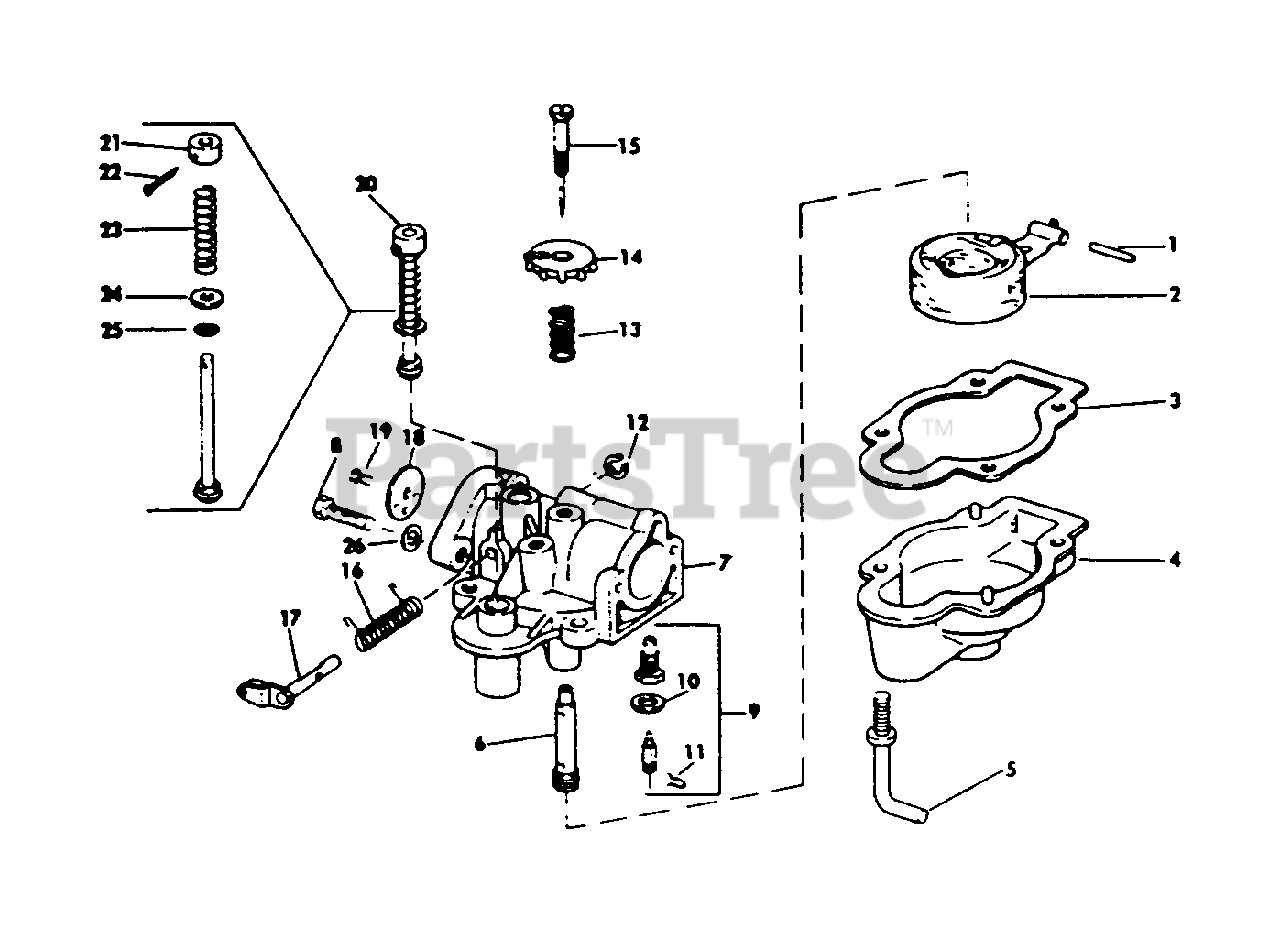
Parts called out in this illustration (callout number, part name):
1	Pin-Float Arm Hinge
2	Float & Arm Assy.
3	Gasket-Float Chamber
4	Chamber-Float
5	Screw-Float Chamber
7	Carb. Body Assy.
9	Float Valve & Seat
10	Washer-Float Valve Seat
11	Clip
12	Grip Ring
13	Spring-Needle Adj.
14	Knob-Needle Adj.
15	Needle Assy.
16	Spring-Throttle
17	Throttle Shaft & Lever Assy.
18	Disc-Throttle
19	Screw-Throttle Shaft Disc.
20	Primer Assy.
21	Knob Primer
22	Cotter Pin
23	Spring Compression
24	Washer-Plain
25	"O" Ring
